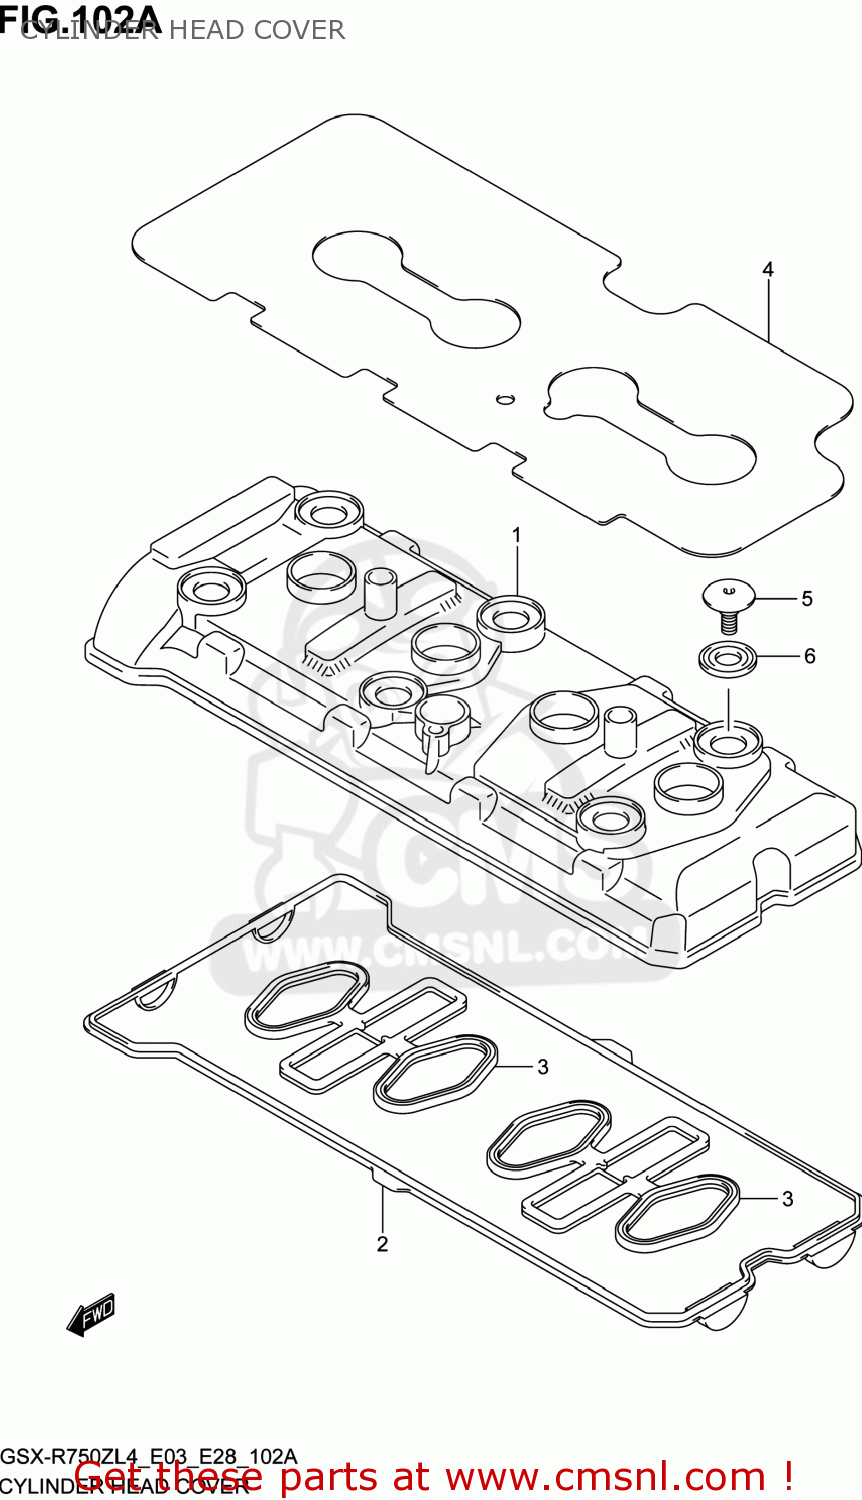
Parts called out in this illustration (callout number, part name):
1	COVER,CYLINDER HEAD
2	GASKET,CYL HEAD COVER NO.1 (NAS)
3	GASKET,CYL HEAD COVER NO.2 (NAS)
4	SHIELD,CYLINDER HEAD COVER
5	BOLT(7X17.5)
6	WASHER,CYL HEAD COVER
